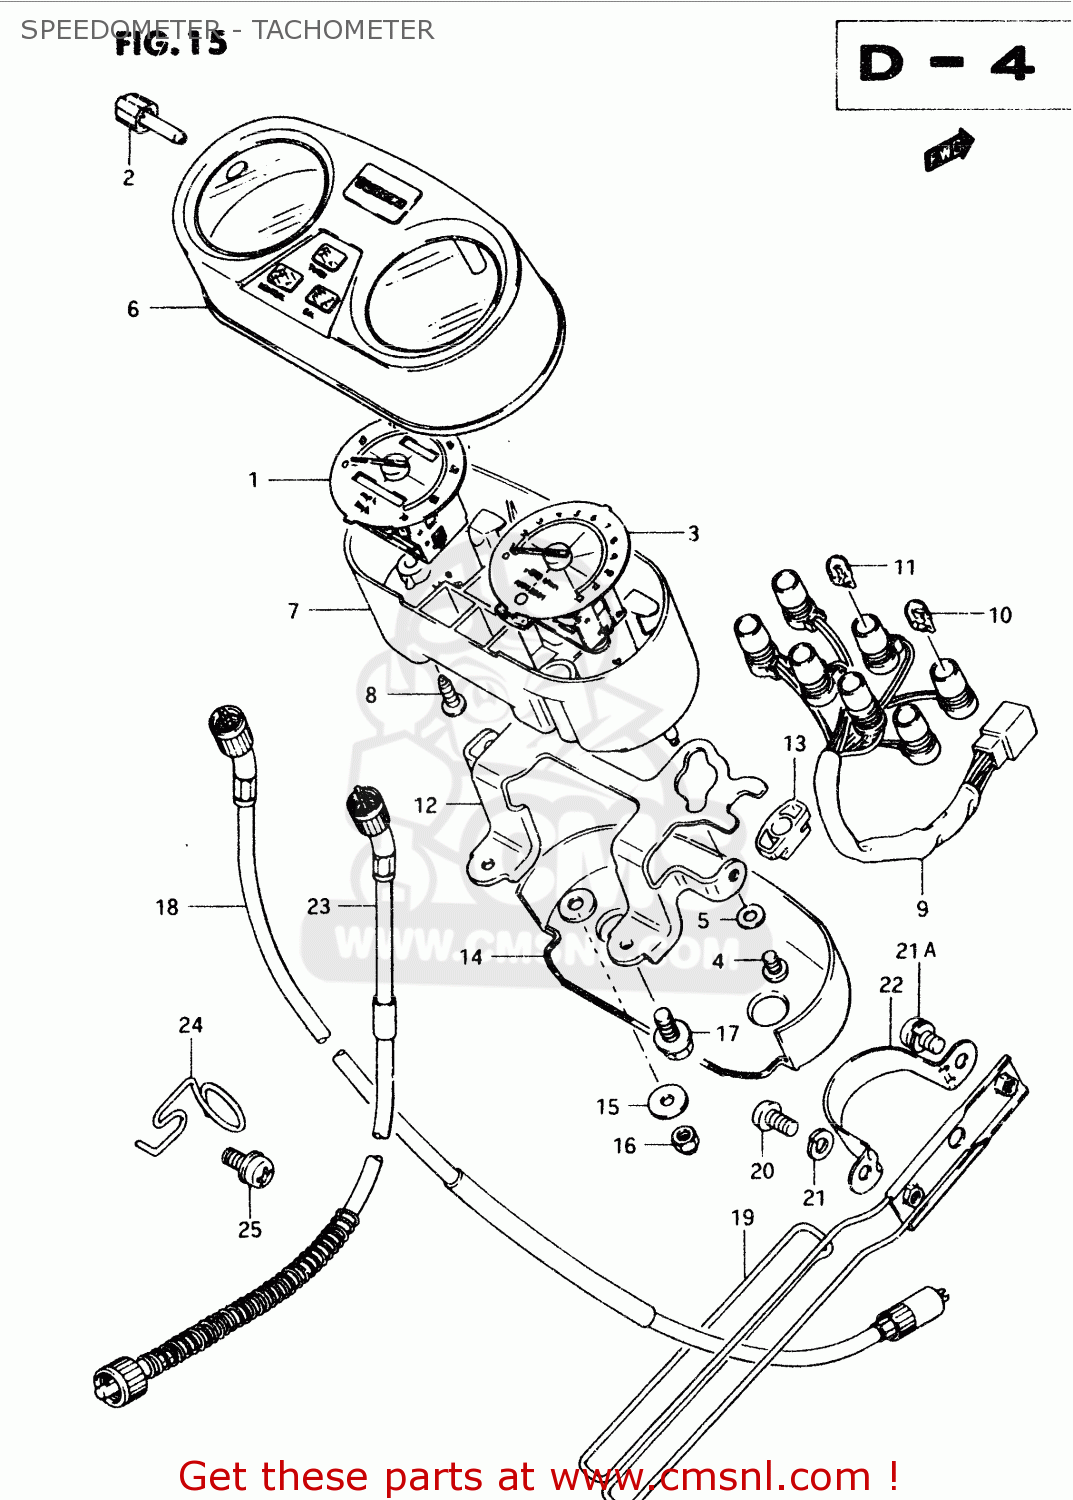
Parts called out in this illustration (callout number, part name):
1	SPEEDOMETER (KILO)
2	KNOB,TRIP METER
3	TACHOMETER
4	SCREW
5	WASHER 4MM
6	HOOD,METER
7	CASE,METER
8	SCREW
9	SOCKET
10	BULB(12V1.7W,T10,WB121)
11	BULB(12V3.4W,T10)
12	BRACKET,METER
13	CUSHION
14	COVER,LWR
15	WASHER
16	NUT
17	BOLT
18	CABLE ASSEMBLY,SPEEDOMETER
19	GUIDE,CABLE
20	SCREW
21	WASHER,LOCK
21A	SCREW
22	CLAMP,CABLE GUIDE
23	CABLE ASSY,TACHOMETER
24	GUIDE,TACHOMETER CABLE
25	SCREW
